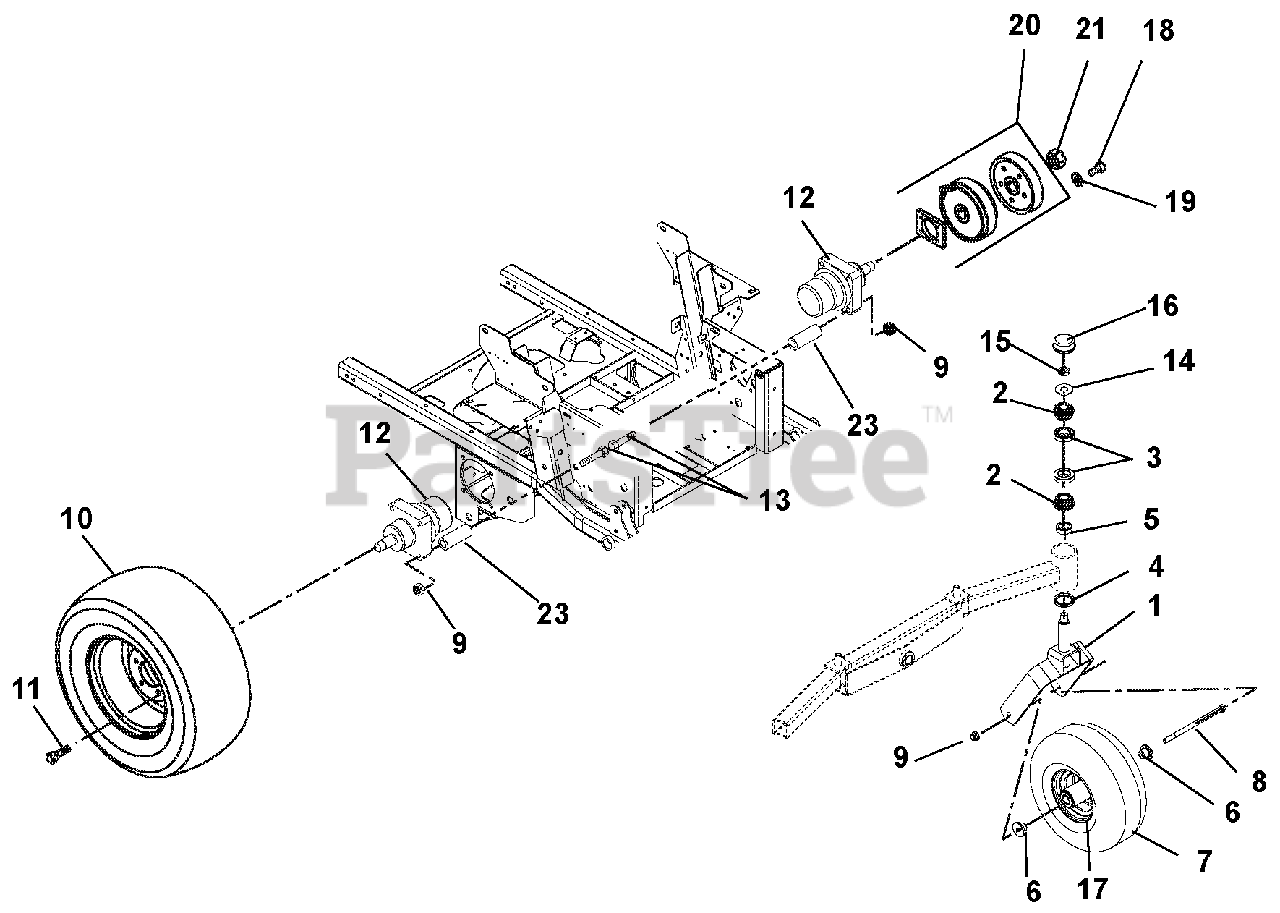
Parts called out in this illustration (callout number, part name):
1	Fork, Front
2	Bearing, Cone
3	Bearing, Cup 2.328 x .465
4	Bearing Seal 1.75 x 2.332 x .312
5	Spacer, 1.258 ID x 1.750 OD x .550
6	Spacer, Wheel
7	Wheel/Tire Assembly 15 x 6-6 Smooth
8	Bolt, Hex .50-13 x 9.00 Grade 5
9	Nut, Locking Top Flange .50-13
10	Tire/Wheel Assembly, 24 x 11.50-12
11	Bolt, Lug .50-20 x 1.38
12	Wheel Motor, 18E (CCW)
13	Bolt, Hex .50-13 x 2.75 (992316, 317, 321, 322)
14	Washer, Flat Steel, .812 x 2.00 x .148
15	Nut, Locking Center Jam .75-16
16	Cap, Dust
17	Bearing, 25mm ID x 52mm OD x 15mm
18	Bolt, Hex .31-18 x 1.50 Grade 8 EP30
19	Waher, Lock .31 x .078
20	Kit, Parking Brake Service
21	Nut, Locking Jam Patch 1.00-20
22	Seal Kit (032550001, Wheel Motor), NS
23	Bushing, .513 x .748 x .129 (992324)
